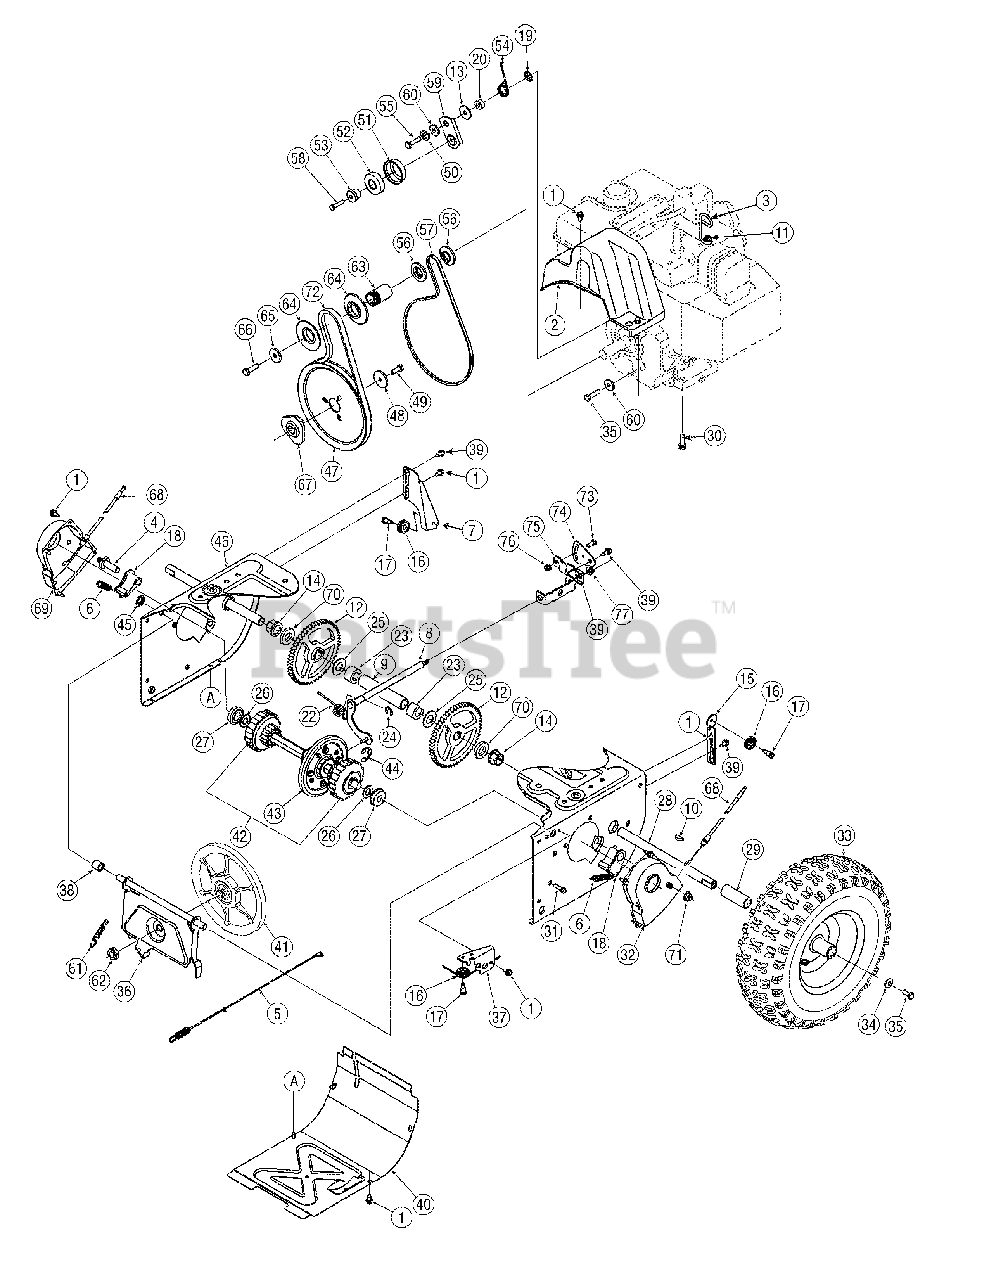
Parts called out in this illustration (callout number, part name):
1	AB Screw, 1/4-20 x 0.625
2	Belt Cover
3	Cable Guide
4	Actuator Shaft
5	Drive Clutch Cable
6	Extension Spring
7	Drive Clutch Cable Guide Bracket
8	Shift Rod Assembly
9	Axle Support Tube
10	Hi Pro Key
11	TT Screw, 5/16-18 x 1.00
12	Gear, 56T
13	Flat Washer
14	Hex Flange Bearing
15	Auger Clutch Cable Guide Bracket
16	Cable Roller
17	C Screw, 1/4-28 x 0.375
18	Dogg Assembly - LH
18	Dogg Assembly - RH
19	Push-on Nut
21	Shift Bracket Spacer
22	Torsion Spring, .750ID x .968 Lg.
23	Spacer
24	E Ring
25	Flat Washer, .76 x 1.49 x .06
26	Flat Washer
27	Ball Bearing
29	Spacer
30	TT Sems Screw, 3/8-16 x 1.0
31	TT Screw, 1/4-20 x 1.0
34	Bell Washer
35	Hex Bolt, 5/16-24 x 0.75
36	Friction Wheel Support Brkt. Assy.
37	Auger Cable Guide Bracket
38	Spacer
39	Shoulder Screw
42	Drive Shaft Assembly
43	Friction Wheel Assembly
43	Friction Wheel Rubber Only
44	Retainer Ring
45	Speed Nut
47	Auger Pulley
48	Flat Washer
49	Hex Bolt, 5/16-24 x 0.875
50	Lock Washer
51	Bearing Sleeve
52	Ball Bearing
53	Spacer
54	Torsion Spring
55	Hex Screw, 5/16-24 x 1.25
56	Pulley Half
57	V-Belt, 2L x 33
58	TT Screw, 1/4-20 x 1.25
59	Drive Clutch Idler Bracket
60	Shoulder Spacer
61	Extension Spring
62	Jam Lock Nut, 5/8-18
63	Spacer
64	Pulley Half
65	Flat Washer
66	Hex Bolt, 3/8-24 x 1.25
67	Pulley Adapter
68	Steering Cable
70	Axle Spacer
71	Flange Lock Nut, 3/8-16
72	V-Belt,.500 x 35.00 Lg
73	Hex Screw, 1/4-20 x .620
74	Speed Selector Pivot Bracket
75	Speed Selector Shift Bracket
76	Flange Lock Nut 1/4-20
77	Rim Wheel Size 16 x 4.8
77	Valve
77	Tire Chains
